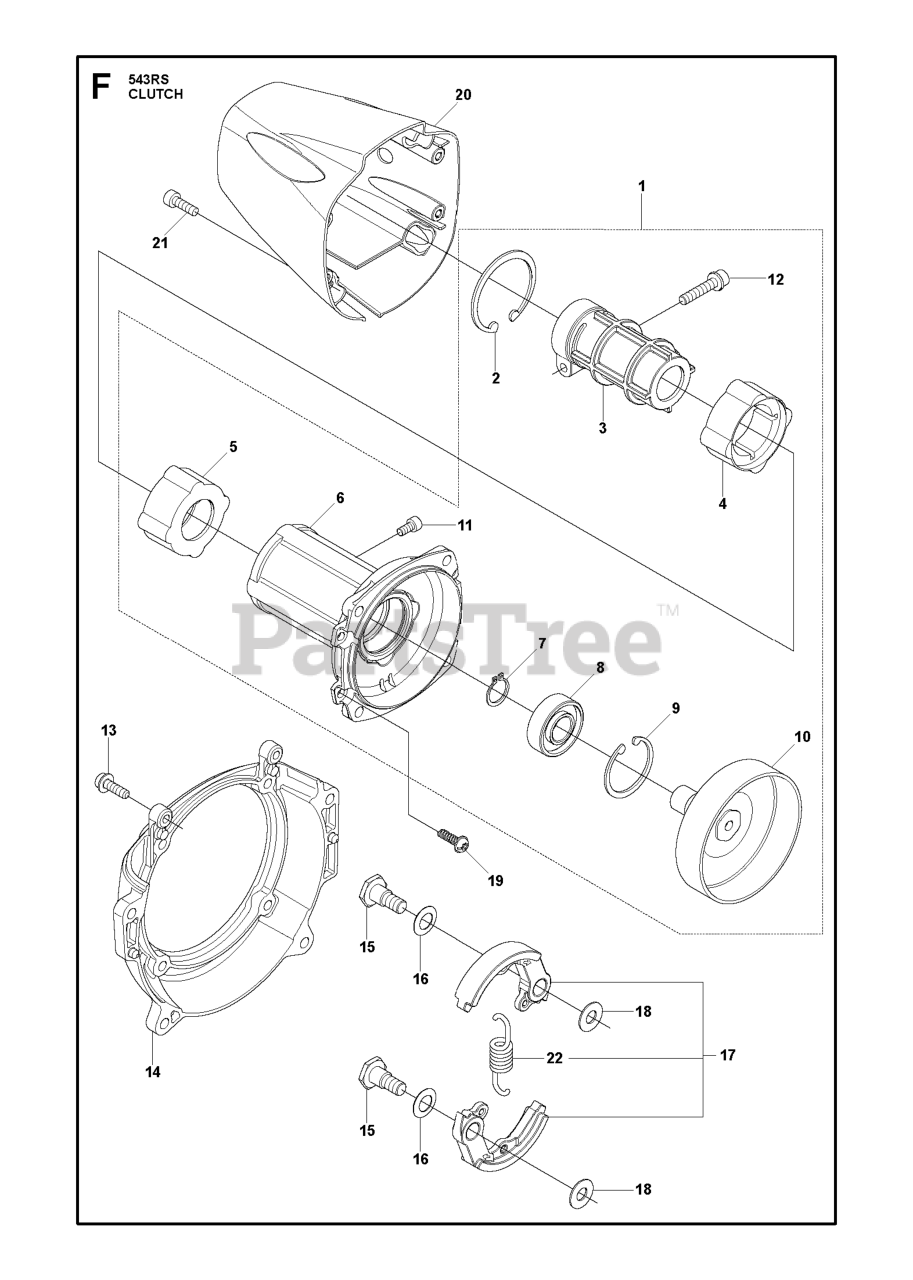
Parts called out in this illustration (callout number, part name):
1	WHEEL.STEER.HUSQ.SR.498.OVMLD
2	AXLE.CAST.IRON
4	SPINDLE.ASM.LH
5	SPINDLE.ASM.RH
6	THRUST WASHER
9	CAP.SPINDLE.BLACK
14	WASHER, LOCK 3/8
15	NUT CROWNLOCK 3/8-24
16	SHAFT.STEER.2HIGH.SPLND.PLATED
19	PLATE.STEER.DDL.NLT/NG
21	ADAPTER.WHEEL.STEER.SPLND.ALUM
22	BEARING.SHAFT.STEER.LOWER.625
26	INSERT.CAP.WHL.STRG.HUSQ.PREM
28	SCREW, 3/8-16X3/4
35	GEAR.SECTOR.PLATE.DDL.
45	WASHER.3/8ID.2-3/8OD.12GA.PLTD
50	NUT LOCK FLG 3/8-16 UNC
53	WASHER.HARDENED
55	SPACER.BRACE.AXLE
58	BOLT.SHOULDER.SECTOR.P
59	WASHER.THURST.SECTOR.S
60	NUT FLANGE LOCK 5/8-11
61	DRAGLINK.LH.BALLSTUD.D
62	DRAGLINK.RH.BALLSTUD.D
63	SCREW
64	RETAINER.CLIP.SPRING.S
65	BRACE.AXLE.FRONT.NLT/N
66	BOLT HEX FGHD 7/16-14 X 3 SERR
67	BUSHING.PM.FRONT AXLE
68	NUT.LOCK.FLANGE.7/16
69	WASHER.1.5X.505X.118
70	BRACKET.FRT.DECK.SUSP.RR.MT431
75	PINION.ZINC PLATED
76	SCREW HEAD SOCKET LRVB
78	THRUST WASHER
122	CAP.GEAR.SECTOR.TEX
